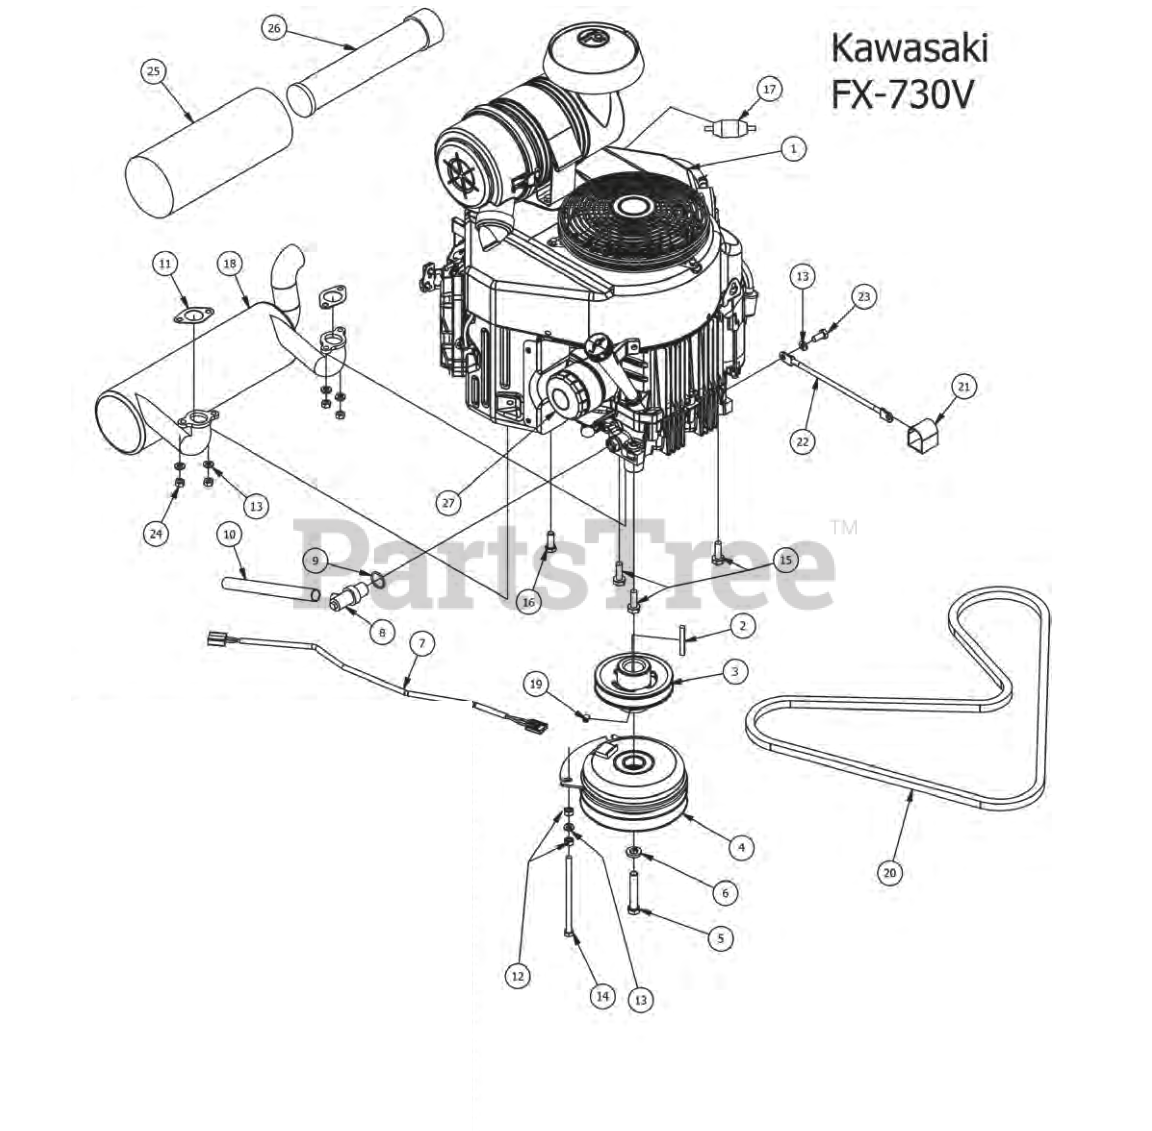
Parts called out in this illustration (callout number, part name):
2	1/4 x 2 Square key Stock
3	4 3/4 Motor Pulley
4	Clutch Assembly
5	7/16" x 2 1/2" Hex Bolt
6	7/16" Lock Washer
7	Clutch Pigtail
10	1/2 Clear Braded Hose Priced/Foot
11	Exhaust gasket
13	5/16" Lock Washer
14	5/16-18 x 5-1/2 GR 5 Hex Bolt
15	3/8 x 1 1/8 bolt
16	3/8" x 1" Hex Bolt
17	Universal inline Fuel Filter
18	Exhaust-2015 Stand On
19	5/16 Set Screw
21	Black Boot For ground cable
22	Ground Cable
23	M8x1.20x20MM Hex head bolt
24	M8-1.25 Zine Nut
25	Canister Air Filter- Outer
26	Canister Air Filter- Inner
27	Oil Filter
